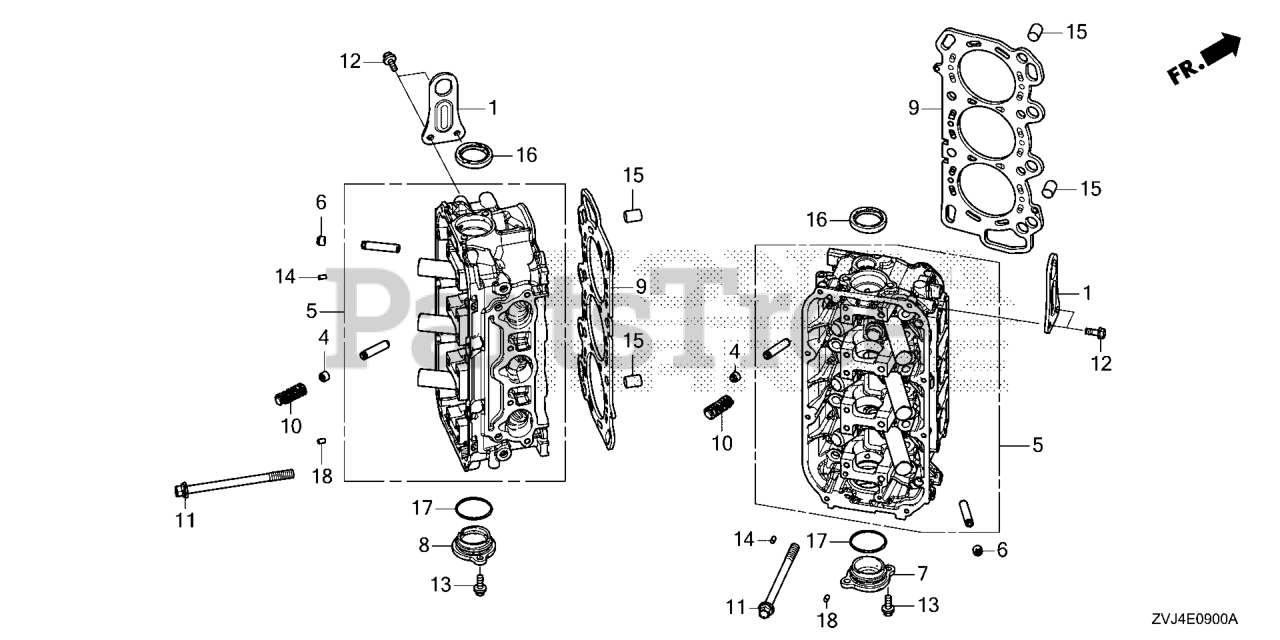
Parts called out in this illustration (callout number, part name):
1	HANGER, ENGINE
2	GUIDE, VALVE (OVER SIZE)
3	GUIDE, EX. VALVE (OVER SIZE)
4	SEAL A, VALVE STEM (NOK)
5	CYLINDER HEAD *NH8* (DARK GRAY)
5	HEAD COMP *NH8*
6	SEAL B, VALVE STEM (NOK)
7	COVER, R. CAMSHAFT THRUST
8	COVER, L. CAMSHAFT THRUST
9	GASKET, CYLINDER HEAD (NIPPON LEAKLESS)
10	MOTION, LOST
11	BOLT-WASHER (12X163)
12	BOLT, FLANGE (8X20)
13	BOLT, FLANGE (8X28)
14	PIN, DOWEL (6X10)
15	PIN, DOWEL (16X22)
16	OIL SEAL (39X53X8) (NOK)
17	O-RING (48.5X2.4)
18	PIN B, DOWEL (6X10)
